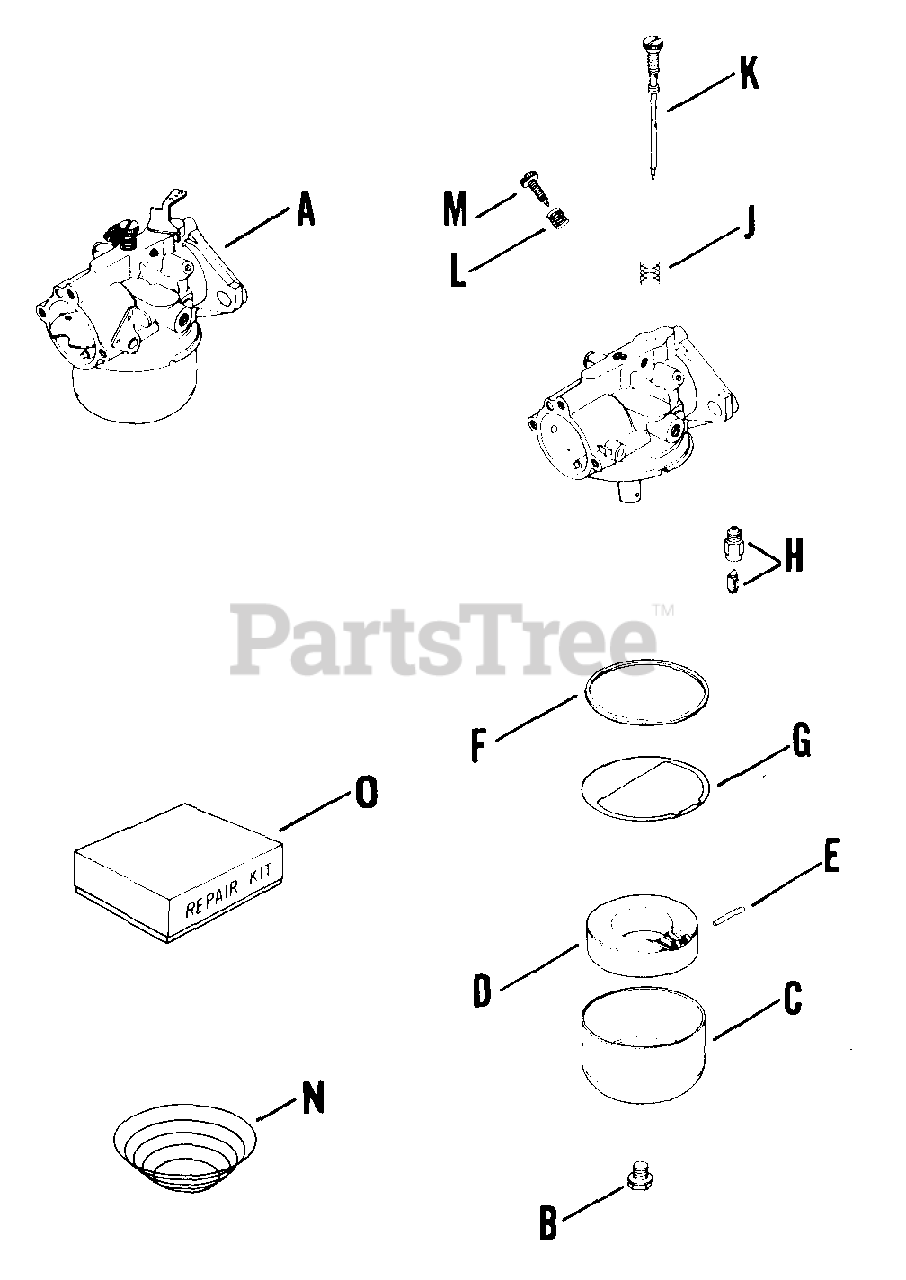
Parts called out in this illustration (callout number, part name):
A	CARBURETOR - USE 41 053 13
B	NUT - DISCONTINUED
D	KIT - USE 25 757 03
G	GASKET - USE 25 041 01
H	NEEDLE - USE 231555
K	NEEDLE - Discontinued
L	SPRING - DISCONTINUED
M	SCREW - DISCONTINUED
O	KIT - USE 25 757 01
